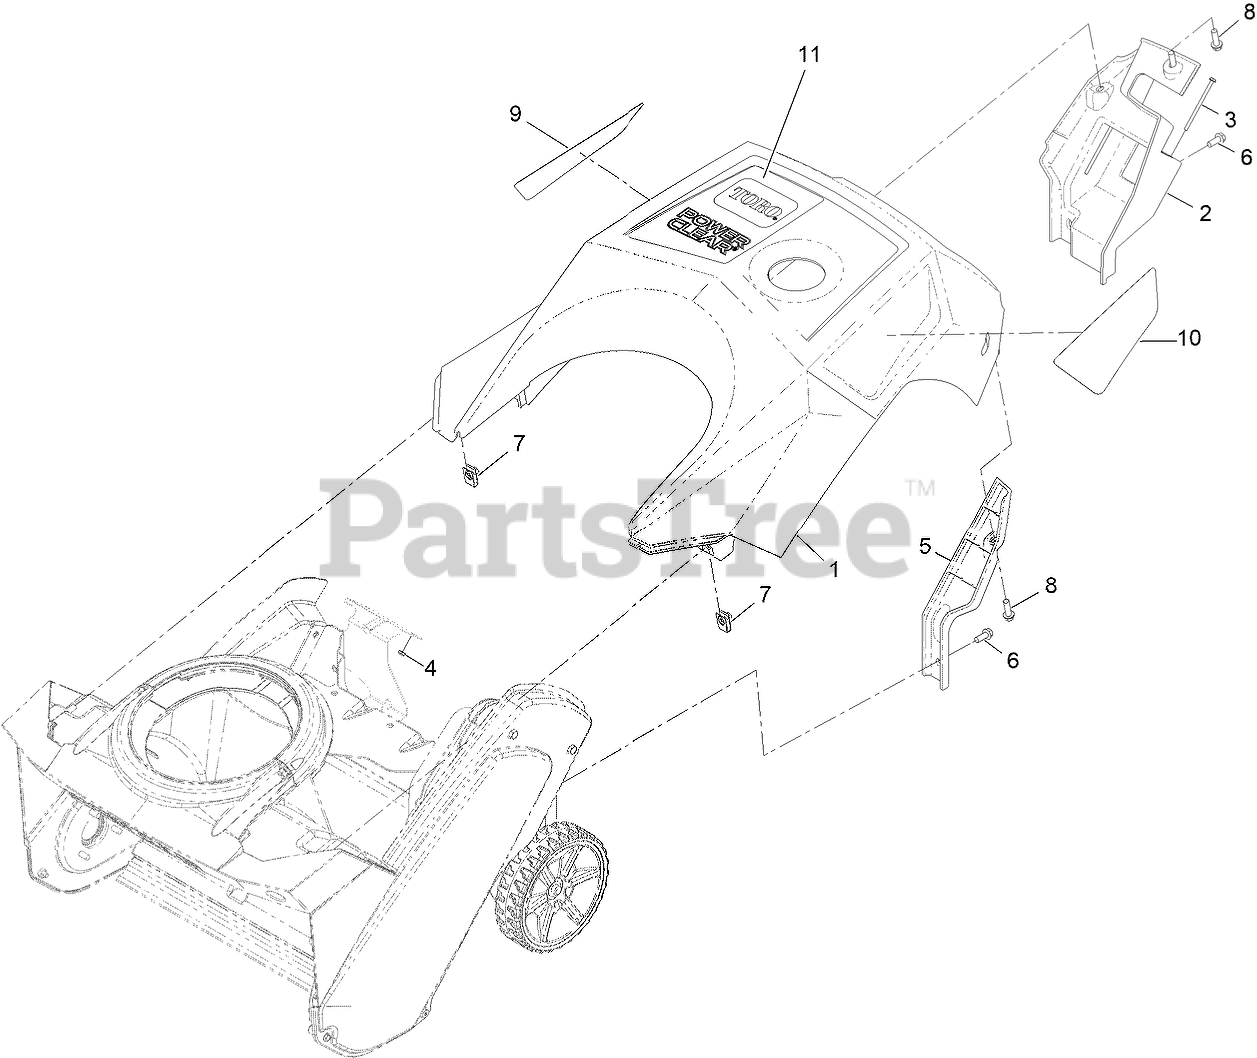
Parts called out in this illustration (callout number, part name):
1	SHROUD-UPPER
2	SHROUD-LOWER, RH
3	SCREW-HWH
4	NUT-HEX
5	SHROUD-LOWER, LH
6	SCREW-HWH
8	SCREW-PLASTITE, HWH
9	DECAL-RH SHROUD ZE
10	DECAL-LH SHROUD ZE
11	DECAL-SHROUD
